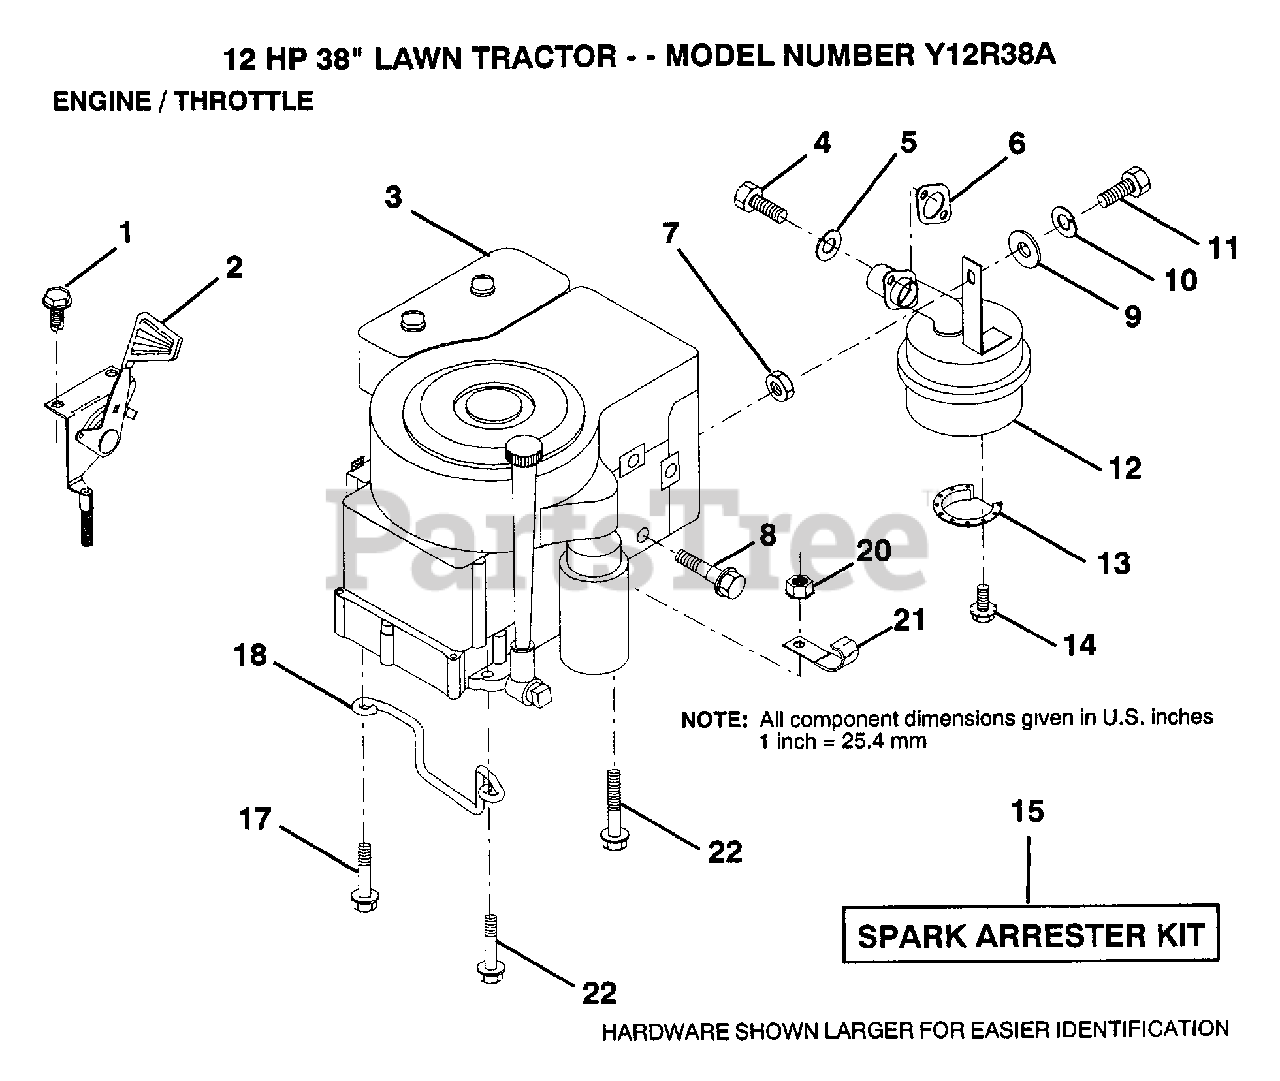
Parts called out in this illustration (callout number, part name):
1	SCREW
2	THROTTLE CONTROL
4	SCREW
5	LOCKWASHER
7	NUT.HEX.5/16-18
8	BOLT T
10	LOCKWASHER
12	MUFFLER
13	DEFLECTOR.222573
17	SCREW LT
18	"KEEPER,DR BELT GR"
20	NUT
21	CLIP T
22	SCREW LT
